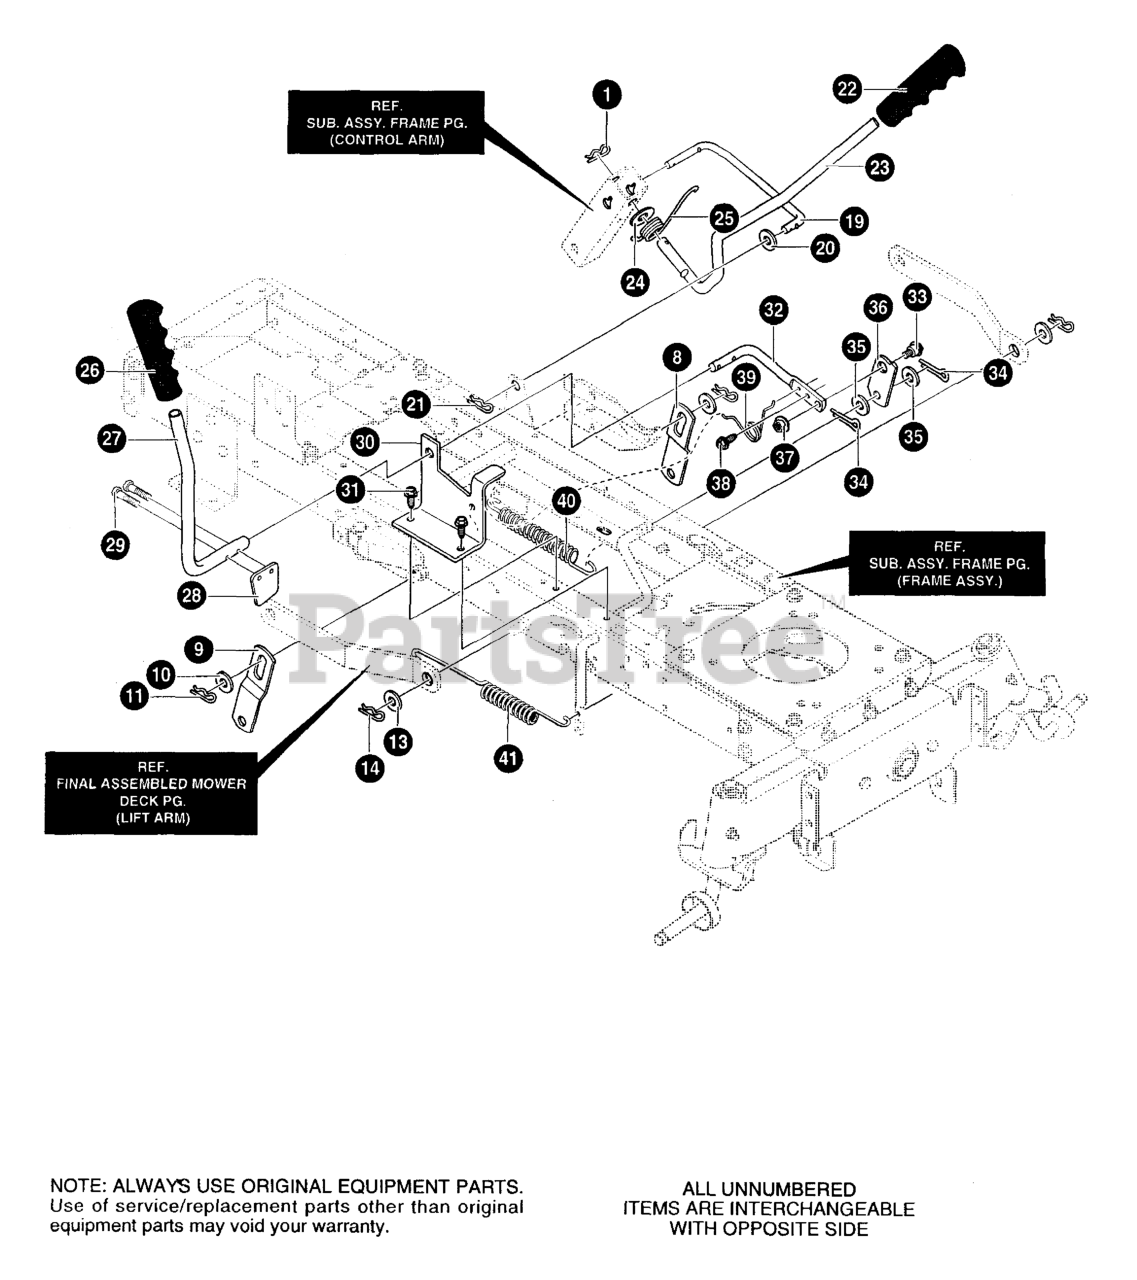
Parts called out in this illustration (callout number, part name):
1	HAIR PIN
8	LINK, LIFT LH
9	LINK-LIFT
10	FLATWASHER
11	PIN, HAIR
13	WASHER, FLAT
14	PIN, HAIR
19	LINK LIFT HANDLE
20	WASHER, FLAT
21	PIN, HAIR
22	GRIP, LIFT 1/2"
23	HANDLE, LIFT
24	WASHER, FLAT .550 x 1.00 x 11 (17X103)
25	TORSION SPRING, .657LG (166X40)
26	Grip, PTO
27	PTO HANDLE
28	PADDLE SWITCH
29	SCREW, THD FORM .246X1.050LG
30	BRACKET, PTO
31	SCREW, 5/16-18 x 0.50 HXFLCA
32	LEVER, PTO
33	BOLT, .50X.75 HHSH 3/8-16 9X39
34	PIN, HAIR.072 DIAX1.13LG
35	WASHER, FLAT .518 x .87 x 16 (17X102)
36	LINK PTO
37	NUT, 3/8-16 HWDFLLK MACK 15X84
38	SCREW, 5/16-18 x 0.75 HHWATAP
39	TORSION SPRING .33LG (166X39)
40	SPRING, TENSION 1.01OD 8.18LG
41	EXTENSION SPRING (165X119)
